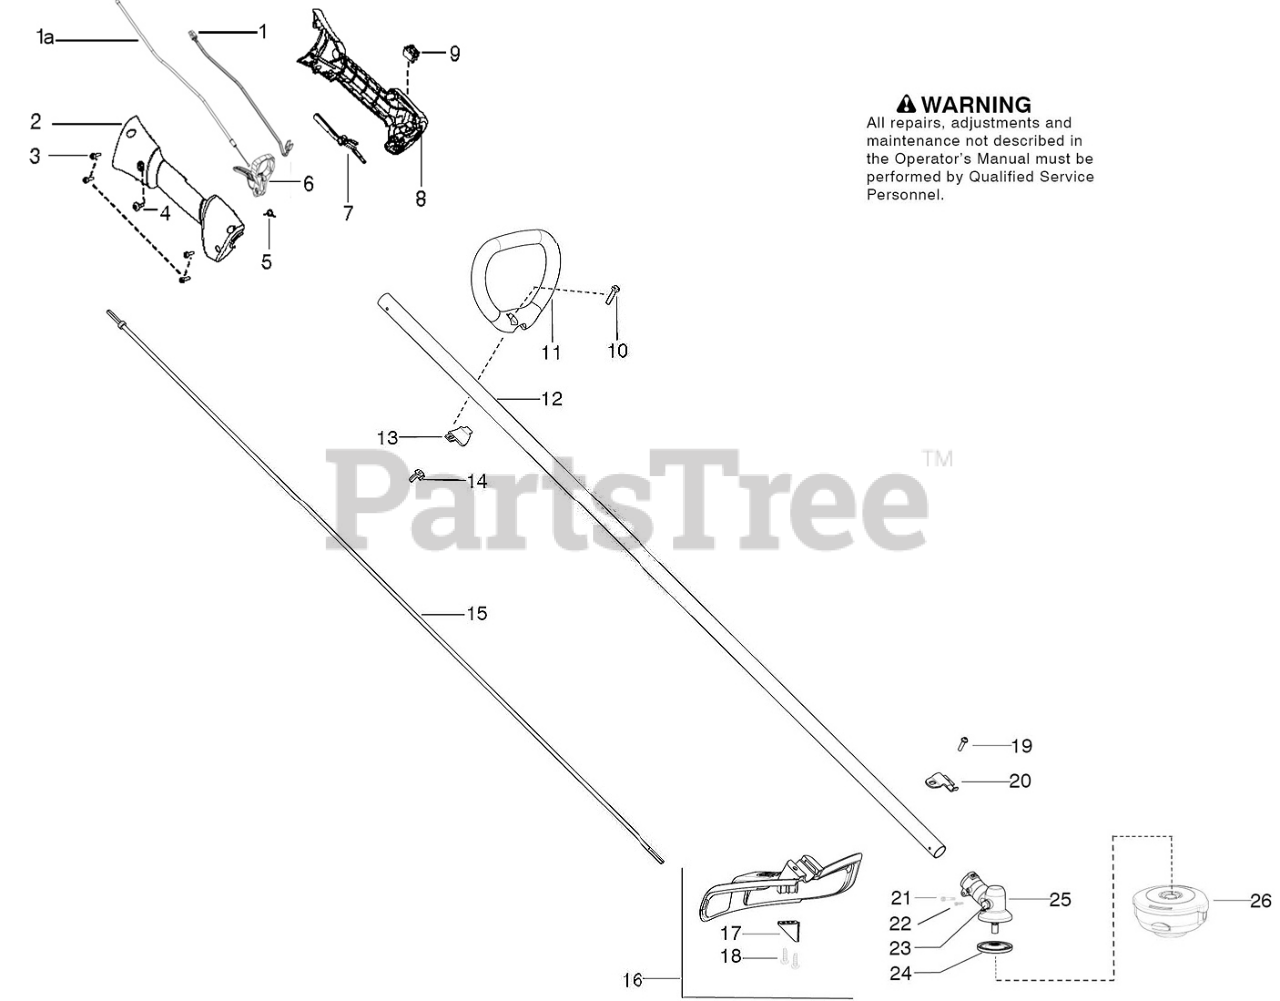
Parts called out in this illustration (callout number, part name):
1	CABLE SHORT CIRCUIT HND
2	HSG THROTTLE RIGHT HVA
5	SPRING TRIGGER
6	TRIGGER THROTTLE HVA ORANGE
7	THROTTLE LOCKOUT HVA ORANGE
8	HSG THROTTLE LEFT HVA
9	SWITCH
10	BOLT, TYPE 2
12	KIT DRIVESHAFT SERVICE
13	CLAMP ASSIST HANDLE
14	WINGNUT, TYPE 2
15	FLEXSHAFT 57"
16	KIT STRAIGHT SHIELD
17	Limiter - Line
18	SCREW 10-14X3/4 PLASTITE
19	SCREW 1/4-20
20	BRACKET SHIELD STRAIGHT SHAFT
21	SCREW 8-32 X 16.51
22	SCREW 8-32 X 16.51 TT SC TRX
23	PLUG GREASE 9MM
24	DRIVE DISC
25	ASSY GEARBOX
26	T25 TRIM HEAD 10MM LH
